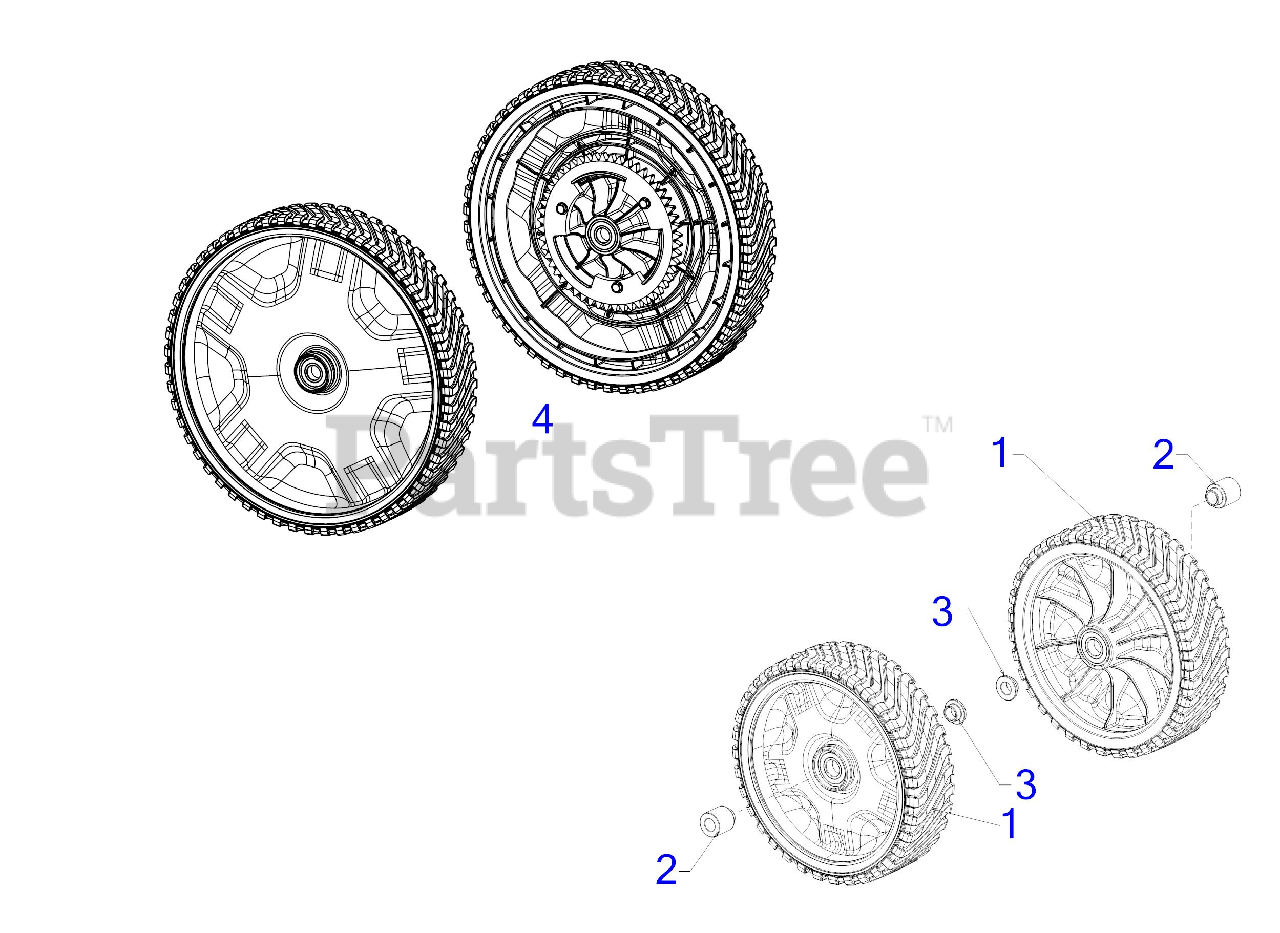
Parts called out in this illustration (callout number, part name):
1	WHEEL ASSEMBLY (7 x 2)
1	BALL BEARING
3	CASTER HUB
4	WHEEL ASSEMBLY (11 x 2)
4	DUST COVER 11"
4	BALL BEARING
